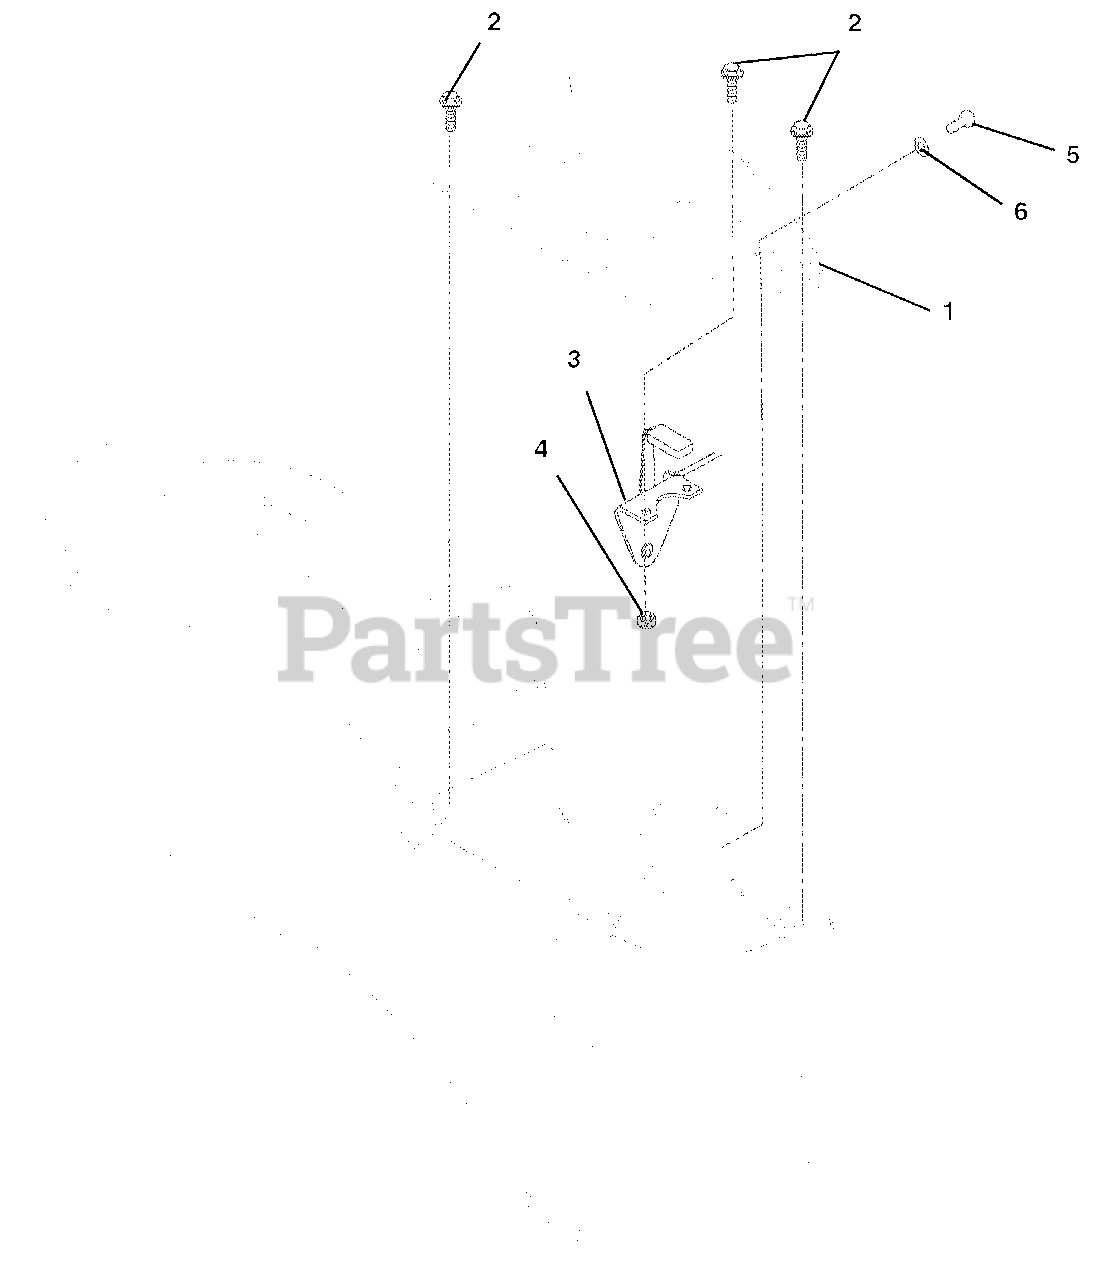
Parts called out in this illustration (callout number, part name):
1	Panel-Control
2	Screw-Machine 10-24 x .50 Hex Washer Head Stainless
3	Throttle, Control
4	Nut-Locking-Nylon 10-24 With Insert
5	Bolt-Hex .31-18 x .75 Grade 5
6	Washer-Flat-Steel .38 x .875 x .083
